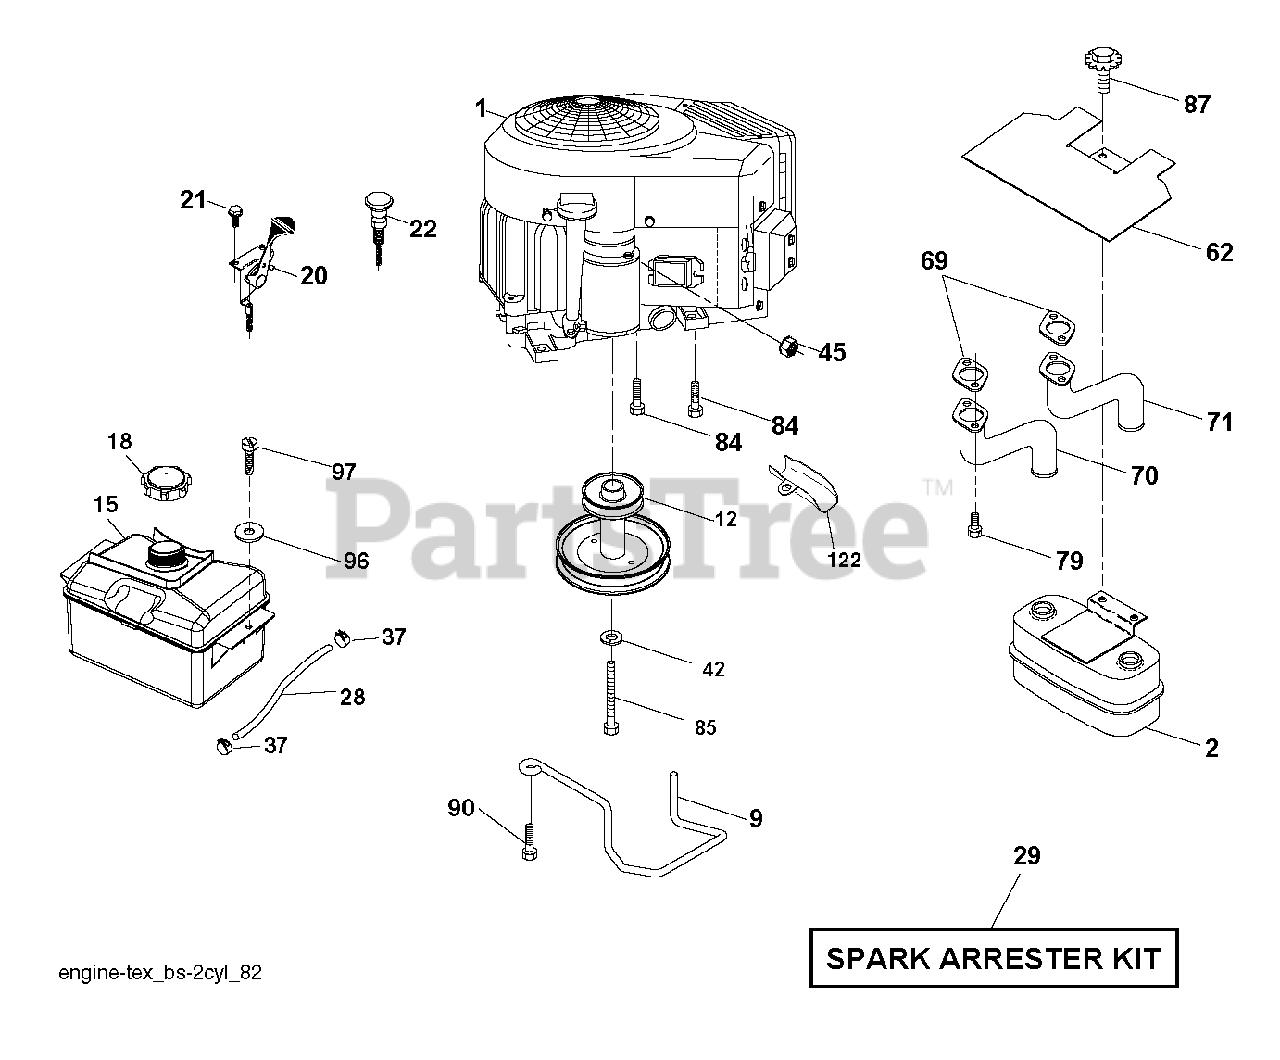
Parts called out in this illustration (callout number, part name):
2	MUFFLER.TWIN.CYL.LOW.TONE
9	KEEPER.BELT.ENGINE.4.2
12	PULLY ENGINE
15	TANK FUEL FRT 1.5 GAL
18	CAP ASM.FUEL.2.25"FR.
20	THROTTLE CABLE
21	SCREW.#10 X 0.750.BOS THREAD
22	CONTROL CHOKE
28	LINE.FUEL.20
29	ARRESTER SPARK (OPTIONAL)
37	HOSE CLAMP
42	LOCKWASHER
45	NUT
62	SHIELD.HEAT.MUFFLER
69	GASKET.MUFFLER
70	TUBE MANIFOLD LH
71	EXHAUST TUBE RH
79	SCREW.SOCKET.HEAD.5/16-18
84	SCREW.3/8-16
85	BOLT HEX 7/16-20X4-1/4"
87	BOLT, 5/16-18 X 1 3/4
90	SCREW 3/8-16X1
97	SCREW HEXWSHR 1/4-20X3/4
122	EXTENSION DRAIN OIL
